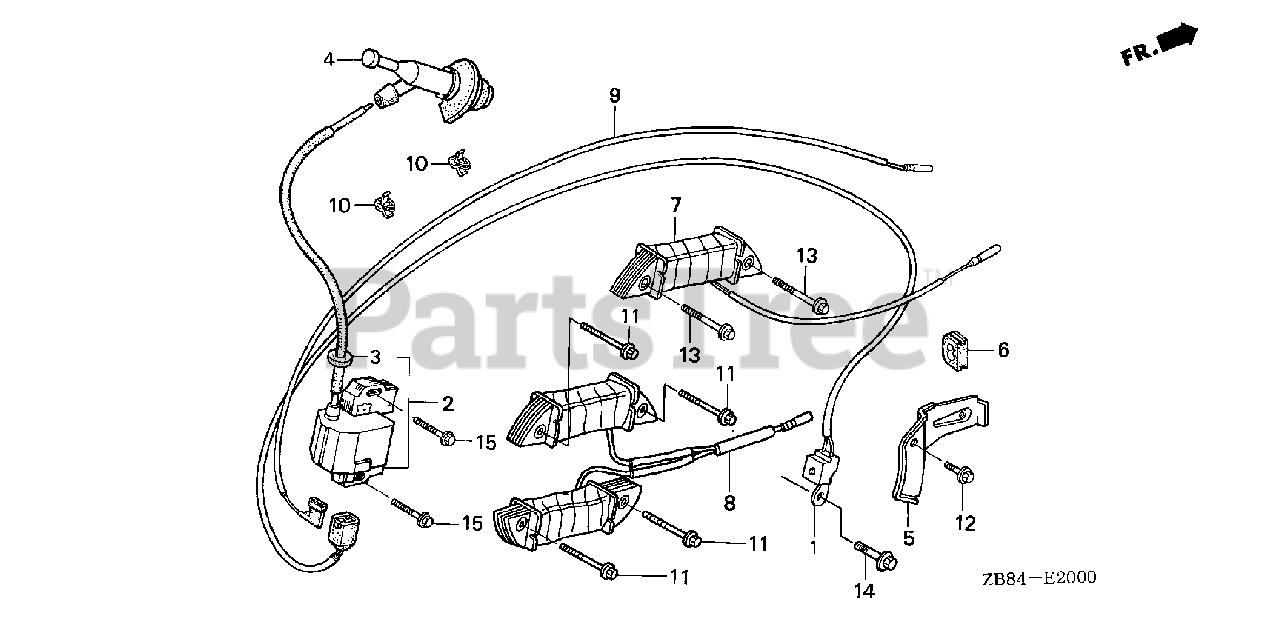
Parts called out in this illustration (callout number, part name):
2	COIL ASSY., IGNITION
4	CAP ASSY., NOISE SUPPRESSOR
5	CLAMP, WIRE
7	COIL ASSY., LAMP (12V/25W)
8	COIL ASSY., CHARGE
9	WIRE, STOP SWITCH (470MM)
11	BOLT, FLANGE (6X40)
12	BOLT, FLANGE (6X12) (CT200)
13	BOLT, FLANGE (6X40)
13	BOLT, FLANGE (6X28)
15	BOLT, FLANGE (6X28)
